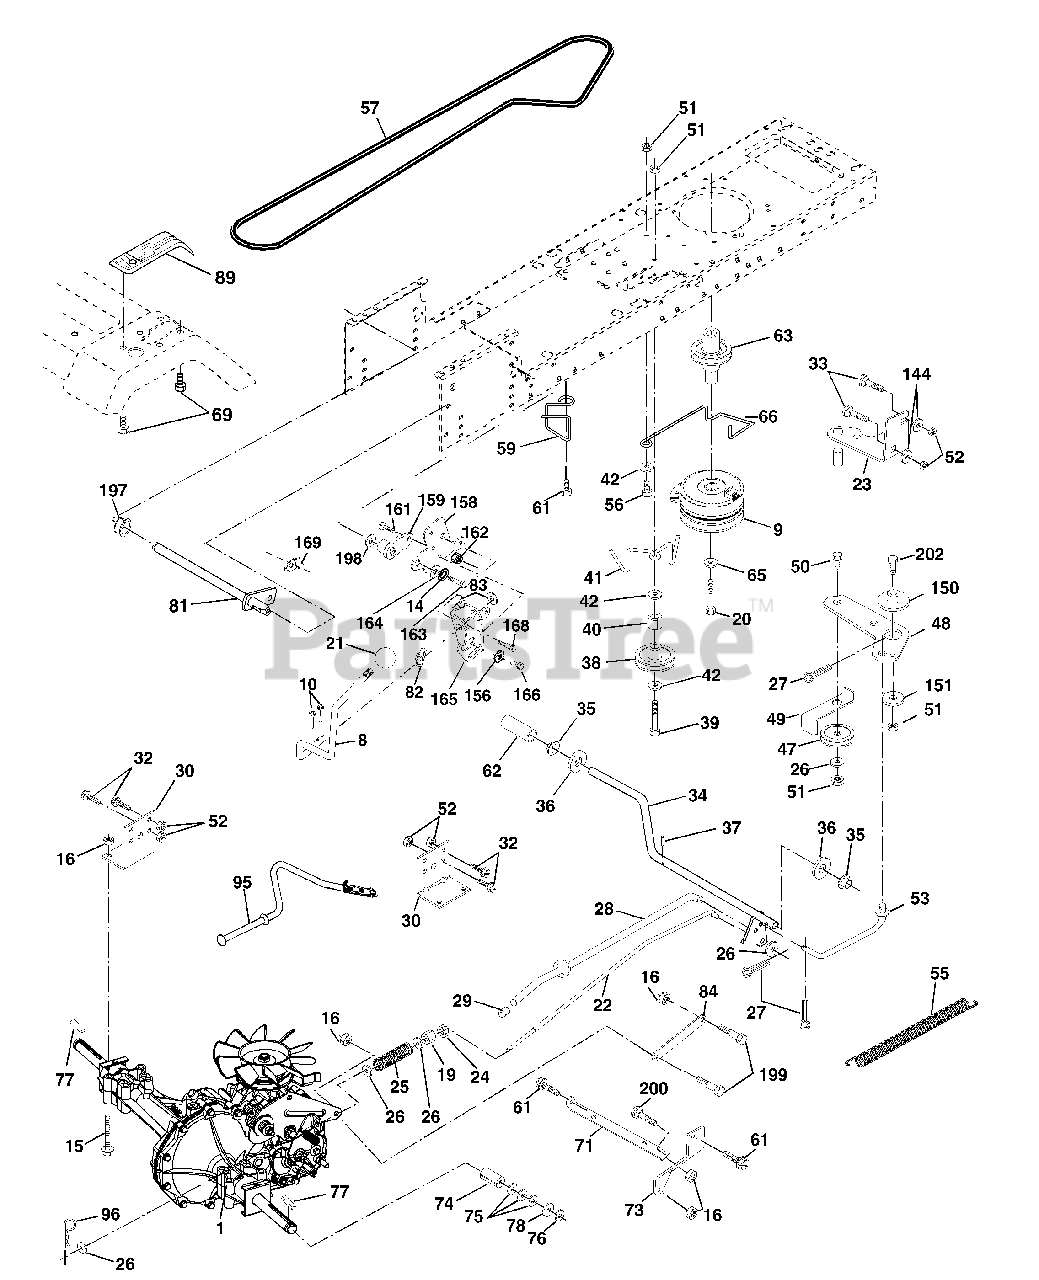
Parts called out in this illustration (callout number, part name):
8	Rod Shift Fender Adjust STLT
9	Clutch Elecric
10	Pin Cotter 1/8 x 1 CAD
14	Washer Lock Hvy Helical
15	Bolt Hex 5/16-18 Unc Flghd
16	Nut Lock Hex W/Ins. 5/16-18 Unc P
19	Nut Lock Hex W/Ins 3/8-16 Unc
20	Bolt, Hex 7/16-20 x 4-1/4 Ga. 5
21	Knob Deluxe 1/2-13 UNC BLK/BLK
22	Rod, Brake Hydro
23	Bracket Asm Mtg CL
24	Nut Hex Jam 3/8-16 UNC
25	Spring, Brake Rod
26	Washer
27	Pin Cotter 1/8 x 3/4 CAD.
28	Rod, Parking Brake
29	Cap,Parking Brake
30	Bracket, Transaxle
32	Bolt Hex Hd 5/16-18 Unc x 3/4
33	Bolt Carriage 5/16-18 UNC x 3/4
34	Shaft, Foot Pedal
35	Bearing, Nylon
37	Pin, Roll
38	Pulley, Idler, Flat
40	Spacer Split
41	Keeper, Belt Idler
42	Washer 13/32 x 13/16 x 12 Ga
47	Pulley, Idler, V-Groove Plastic
48	Bellcrank Clutch Grnd Drv STL
49	Retainer, Belt Style Spring
50	Bolt Hex Hd 3/8-16 Unc x 1-1/2
52	Nut Crown Lock 5/16-18
53	Link, Clutch
55	Spring, Return, Clutch
56	Bolt, Fin Hex 3/8-16 UNC x 1 1/4
57	V-Belt, Ground Drive
59	Keeper, Center Span
61	Screw 3/8-16 x 3/4
62	Cover, Pedal
63	Pulley, Engine
65	Washer Lock Hvy HLCL Spr 7/16
66	Keeper Belt Engine
69	Screw Hex Wsh Hi-Lo 1/4-1/2 Unc
71	Strap Torque Lh Hydro
73	Strap Torque Rh Hydro
74	Spacer, Axle
75	Washer 25/32 x 1-1/4 x 16
77	Key, Square
78	Washer 25/32 x 1-5/8 x 16
81	Shaft Asm Cross Tapered
82	Spring Torsion T/A
83	Washer 17/32 x 3/4 x 16 Ga.
84	Link Transaxle
89	Console, Shift
95	Control Asm. Bypass Hydro
96	Retainer Spring 1" Zinc/Cad
144	Washer 11/32 x 5/8 x 16 Ga.
150	Bushing Bellcrank Grd Drive
151	Washer 13/32 x 2 x 10 Ga.
156	Washer Srrted 5/16ID x 1.125
158	Bracket Shift Mount
159	Hub Tapered Flange Shift Lt
161	Bolt Rdhd Sqnk 1/4-20 x 3/4 Gr 5
162	Nut Crownlock 1/4-20 Unc
163	Bolt Hex Fin 1/4-20 Unc x 1 Gr 5
164	Washer 5/8 x .281 x 10 Ga
165	Bracket Pivot Lever
166	Screw 5/16-18 x 5/8
168	Bolt Shoulder 5/16-18 x .561
169	Plate Fastening STLT/CRD
197	Nyliner Snap 5/8" ID
198	Washer Nyl 7/8 ID x .105 Hyd
199	Bolt Shoulder 5/16-18 Unc
200	Bolt Rdhd Sqnk 5/16-18 Unc x 1
201	Screw Thdrol 3/8-16 x 3/4
